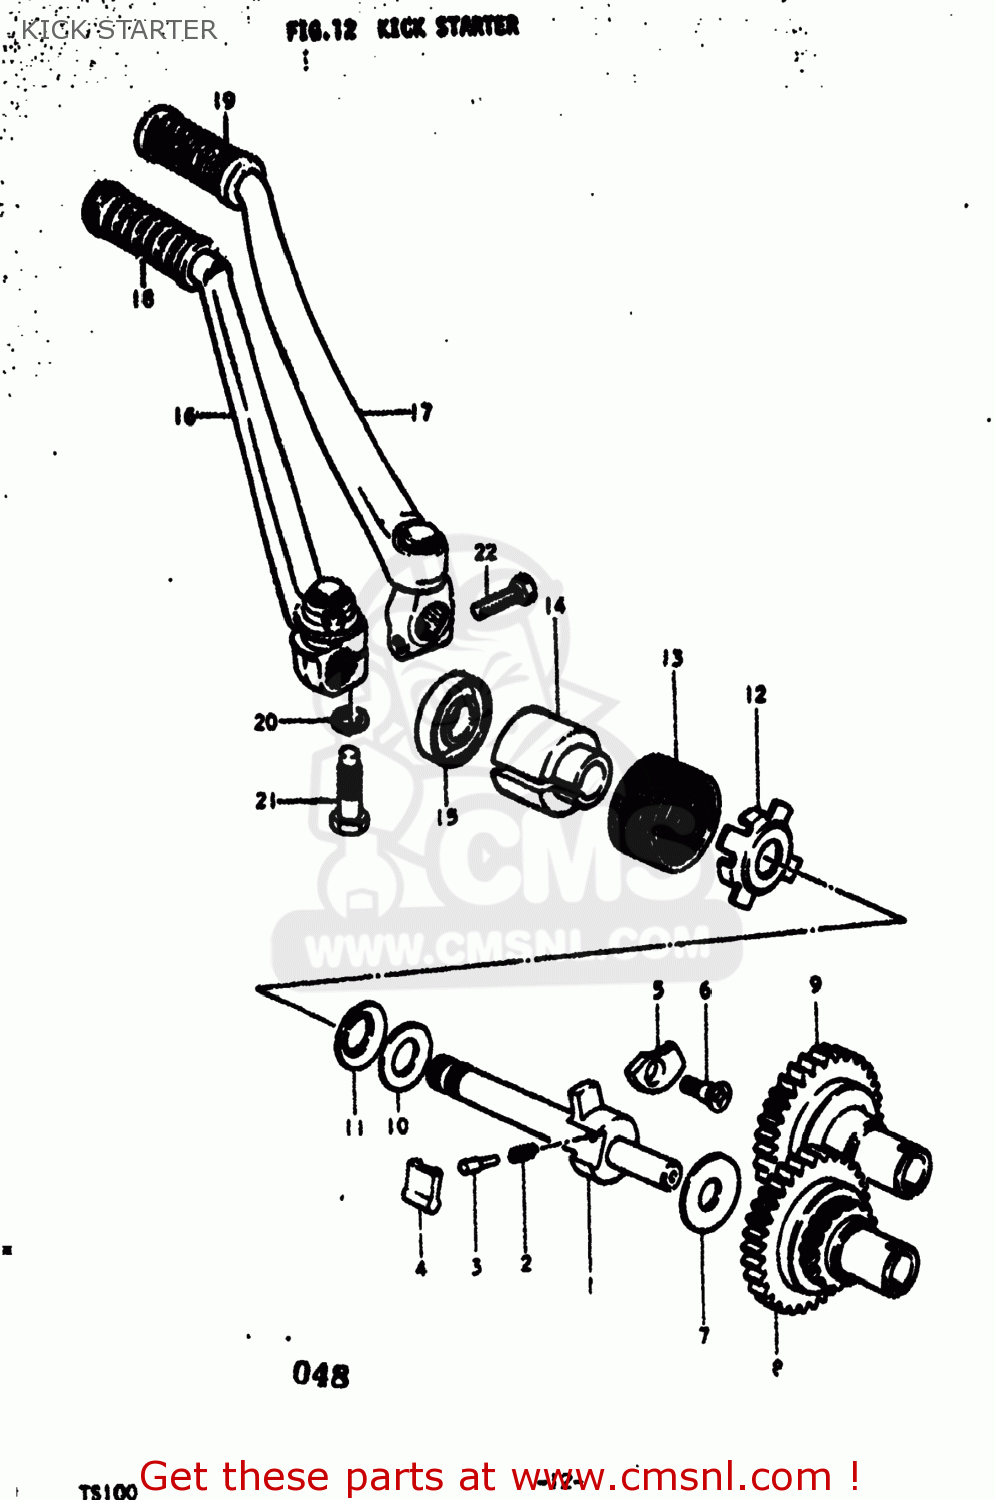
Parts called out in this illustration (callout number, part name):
1	SHAFT,KICK STARTER
2	SPRING
3	PIN(5X15.5)
4	PAWL,KICK STARTER
5	LIFTER,KICK STARTER PAWL
6	SCREW(6X19)
7	WASHER
8	GEAR,KICK STARTER DRIVE
9	GEAR,KICK STARTER DRIVE
10	WASHER(16X30X0.5)
11	WASHER
12	HOLDER,KICK SHAFT SPRING
13	SPRING
14	GUIDE,KICK SHAFT SPRING
15	SEAL,OIL(16X30X8)
16	LEVER ASSEMBLY,KICK STARTER
17	LEVER ASSEMBLY,KICK STARTER
18	RUBBER,KICK STARTER PEDAL
19	RUBBER,KICK STARTER PEDAL
20	LOCK WASHER
21	BOLT(10X37.5)
22	BOLT
